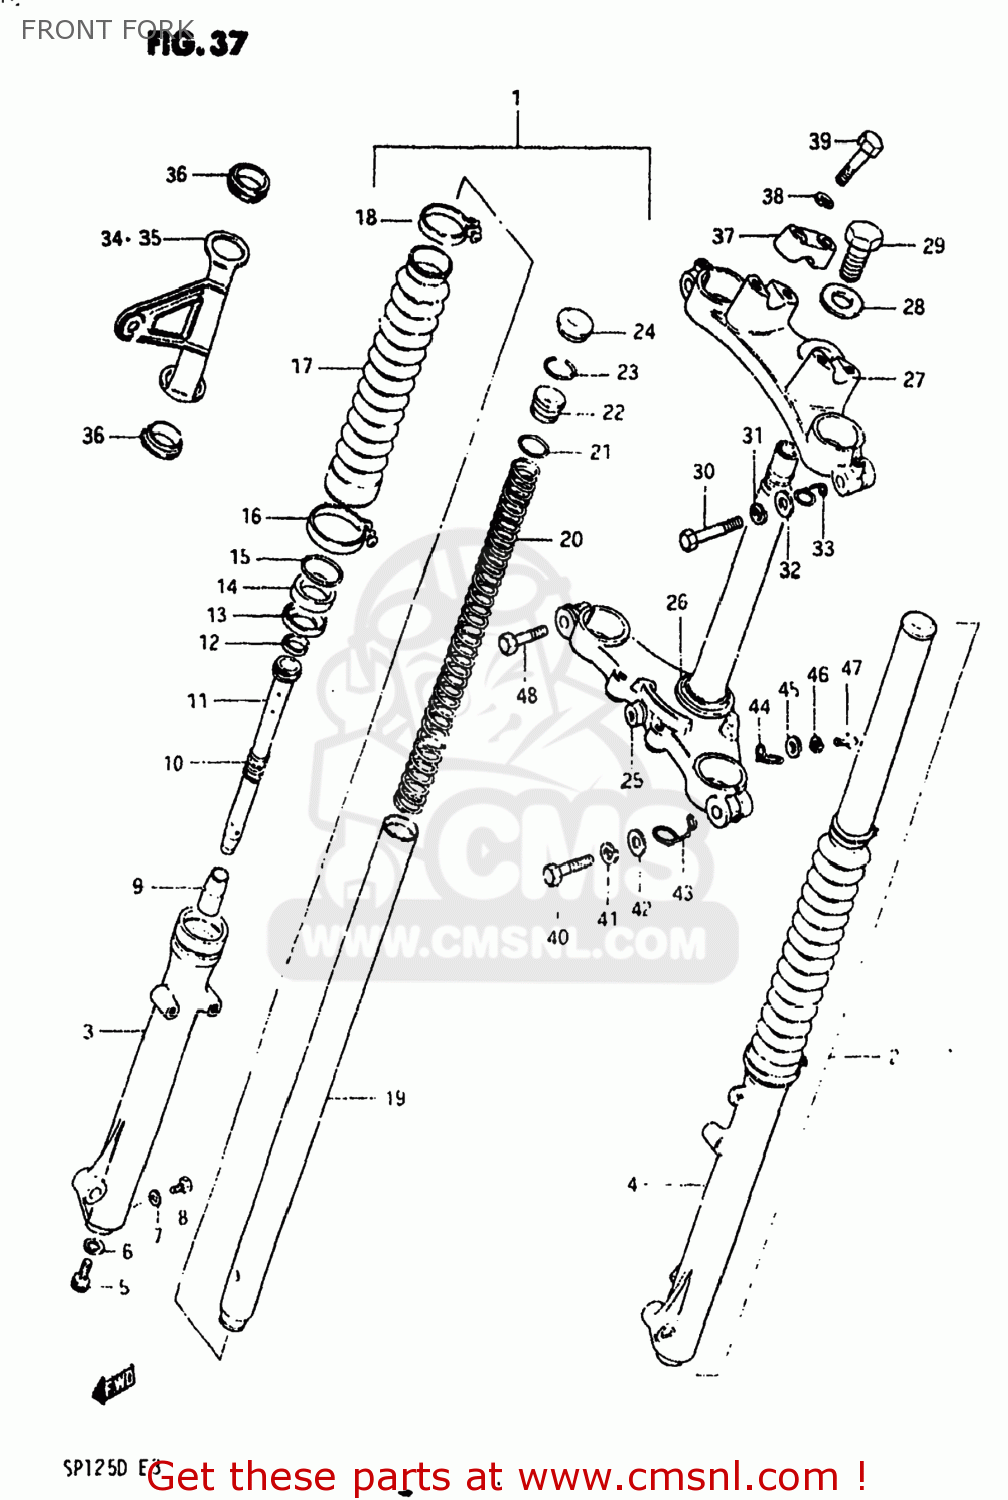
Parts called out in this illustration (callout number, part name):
1	DAMPER ASSEMBLY,RIGHT
2	DAMPER ASSEMBLY,LEFT
3	TUBE,FORK,OUTER,RIGHT
4	TUBE,FORK,LEFT,OUTER
5	BOLT(8X27)
6	GASKET (NAS)
7	GASKET,DRAIN,PLUG (NAS)
8	BOLT
9	PIECE,OIL LOCK
10	SPRING,REBOUND
11	CYLINDER,FRONT FORK
12	RING,PISTON
13	SPACER
14	OIL SEAL,FRONT FORK
15	CIRCLIP,FORK OIL SEAL
16	CLAMP
17	BOOT
18	BAND
19	TUBE,FORK,INNER
20	SPRING,FRONT FORK
21	O RING
22	SEAT,SPRING
23	RING,STOPPER
24	CAP,FRONT FORK
25	STEM, STEERING
26	RACE,STEERING OUTER LWR
27	HEAD,STEERING STEM
28	WASHER,STEM HEAD(10.5X30X3.2)
29	BOLT,FORK INNER TUBE
30	BOLT
31	LOCK WASHER
32	WASHER
33	GUIDE,CABLE
34	BRACKET,HEADLAMP,RIGHT
35	BRACKET,HEADLAMP,LEFT
36	CUSHION,HEADLAMP BRACKET
37	HOLDER,HANDLEBAR
38	LOCK WASHER
39	BOLT,HANDLE HOLDER
40	BOLT 12X45
41	WASHER,LOCK 12
42	WASHER
43	GUIDE,CABLE
44	CLIP
45	WASHER
46	LOCK WASHER
47	SCREW 6X12
48	BOLT
